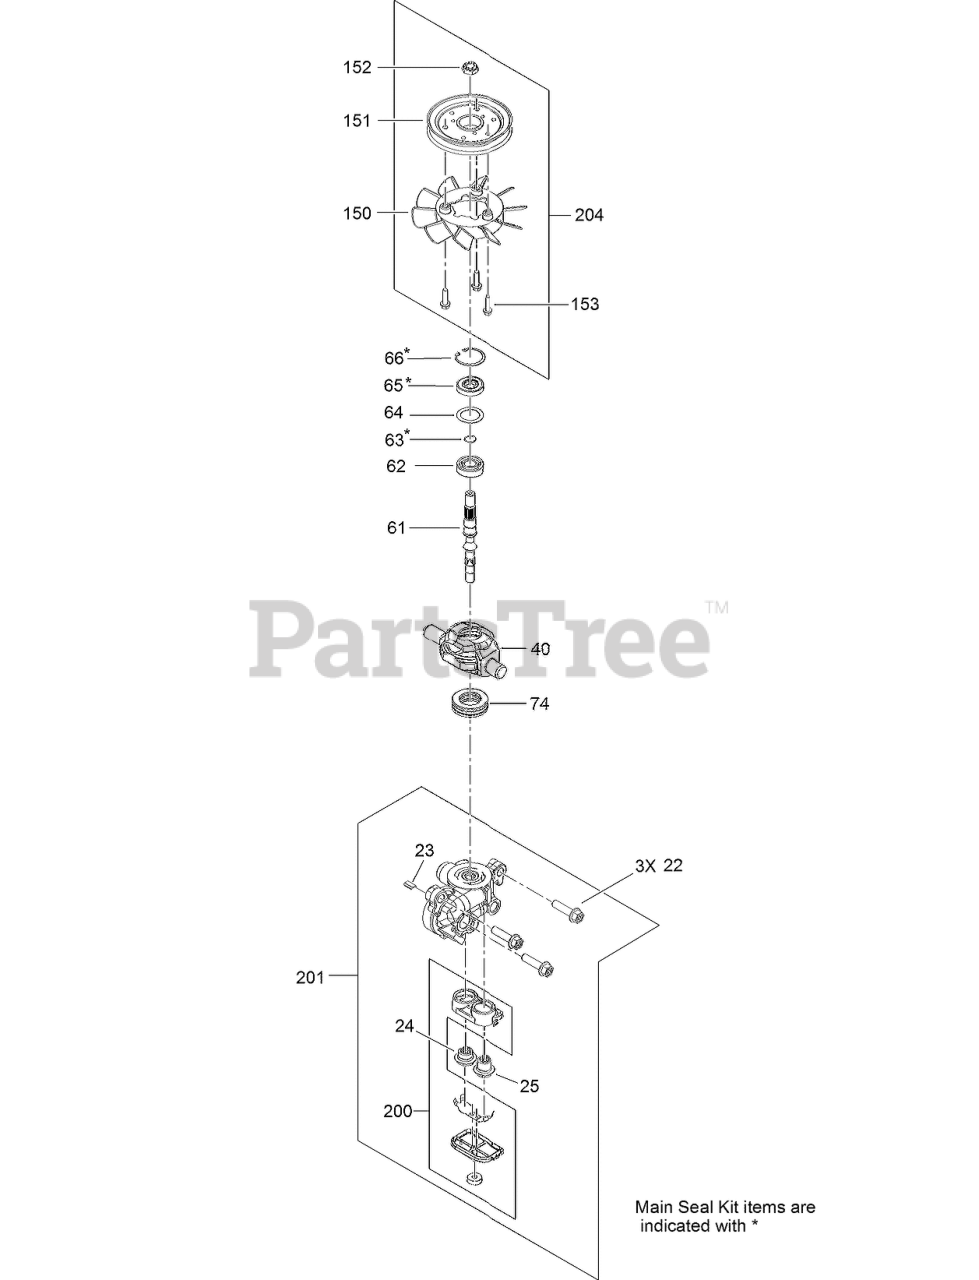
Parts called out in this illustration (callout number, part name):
22	SCREW-HFHC
23	PLATE-BYPASS
24	CHECK PLUG ASM
25	CHECK PLUG ASM
40	TRUNNION-PLATE, SWASH
61	SHAFT-INPUT
62	BEARING-SHAFT, BALL
63	RING-RETAINING, WIRE
64	SPACER
65	SEAL-LIP
66	RING-RETAINING
74	BEARING-THRUST, BALL
150	FAN
151	PULLEY ASM
152	NUT-HEX JAM
200	FILTER KIT
201	CENTER SECTION KIT
204	FAN PULLEY KIT
